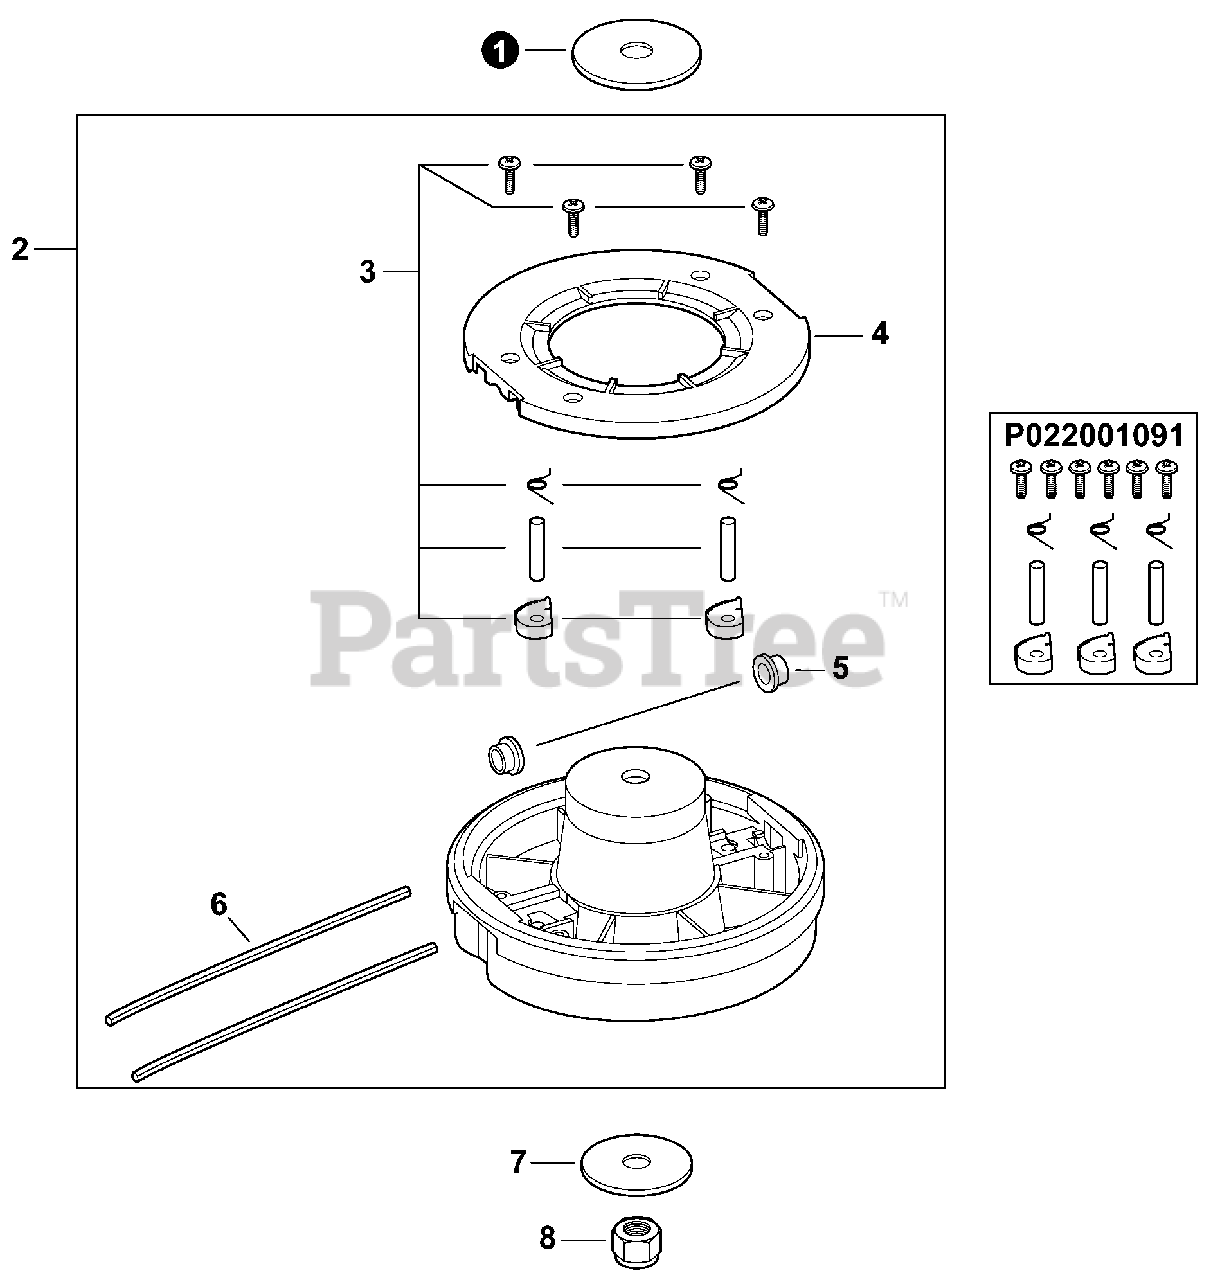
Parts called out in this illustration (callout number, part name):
2	TRIMMER HEAD, RAPID-LOADER - 2 LINE
3	PAWL KIT
4	COVER, TOP
5	EYELET (PACKAGE OF 3)
6	LINE, TRIMMER - 0.095 DIA. (PKG. OF 20)
7	WASHER 10
8	NUT, LOCK
